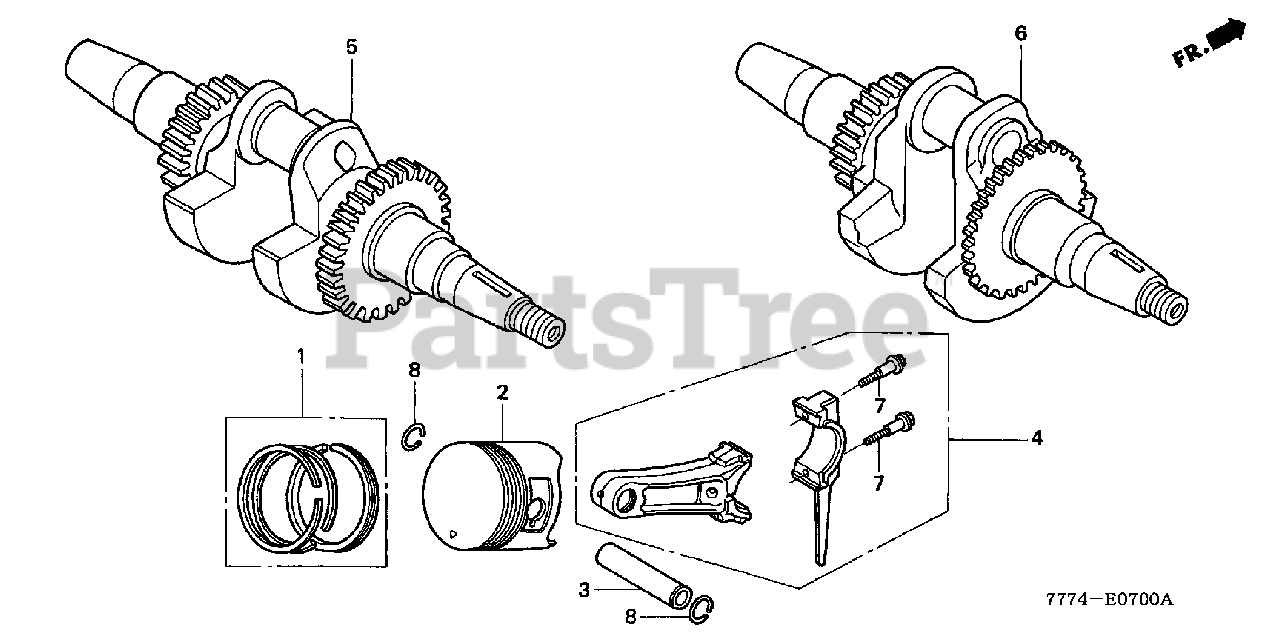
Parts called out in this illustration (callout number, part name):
1	RING SET, PISTON (STD)
1	RING SET, PISTON (STD) (NIPPON)
1	RING SET, PISTON (OS 0.25)
1	RING SET, PISTON (OS 0.25) (NIPPON)
1	RING SET, PISTON (OS 0.50)
1	RING SET, PISTON (OS 0.50) (NIPPON)
1	RING SET, PISTON (0.75)
1	RING SET, PISTON (0.75) (NIPPON)
2	PISTON (STD)
2	PISTON (OS 0.25) Use up to Engine SN 1645601.
2	PISTON (OS 0.25) Use from Engine SN 1645602.
2	PISTON (OS 0.50)
2	PISTON (0.75) Use up to Engine SN 1645601.
2	PISTON (0.75) Use from Engine SN 1645602.
3	PIN, PISTON
4	ROD ASSY., CONNECTING
6	CRANKSHAFT (VE-TYPE)
6	CRANKSHAFT
7	BOLT, CONNECTING ROD
8	CLIP, PISTON PIN (18MM)
